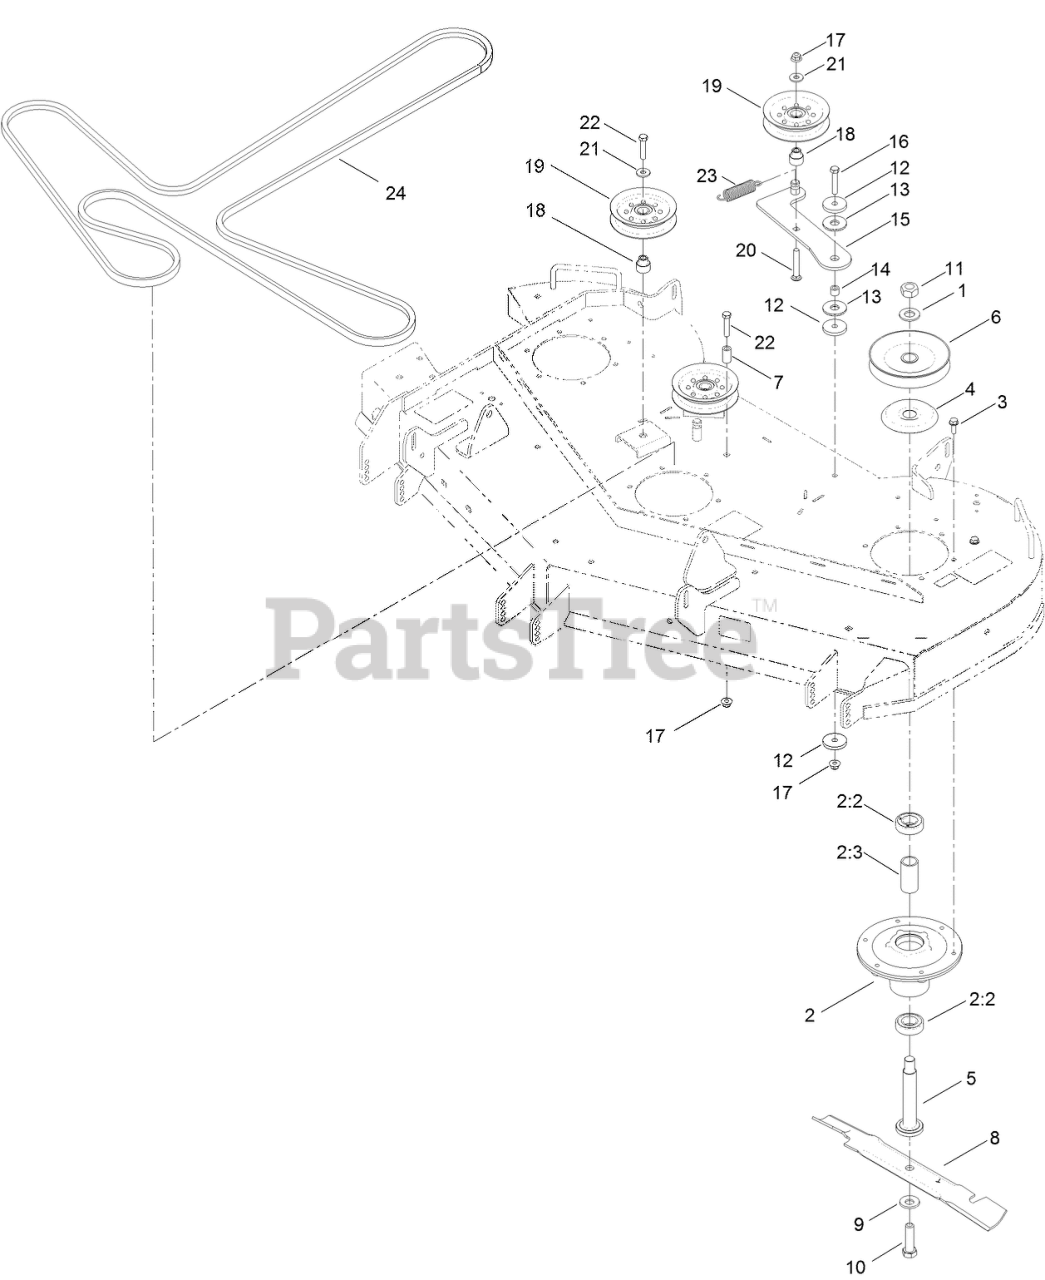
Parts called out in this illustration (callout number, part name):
1	WASHER
2	SPINDLE ASM
2:2	BEARING-BALL
2:3	SPACER-BEARING
3	SCREW-TAPTITE
4	SHIELD-BEARING
5	SHAFT-SPINDLE
6	PULLEY
7	SPACER
8	BLADE-MULCH, 18.75 INCH
9	WASHER-BELLEVILLE
10	SCREW-BLADE
11	NUT-HEX
12	WASHER-PLAIN
13	WASHER-FRICTION, COMPOSITE
14	BUSHING-LEVER, LIFT
15	ARM-IDLER
16	SCREW-HH
17	NUT-HF, NI
18	BUSHING-IDLER
19	PULLEY-IDLER
20	SCREW-CARR
21	WASHER-HARDENED
22	SCREW-HH
23	SPRING-EXTENSION
24	V-BELT
